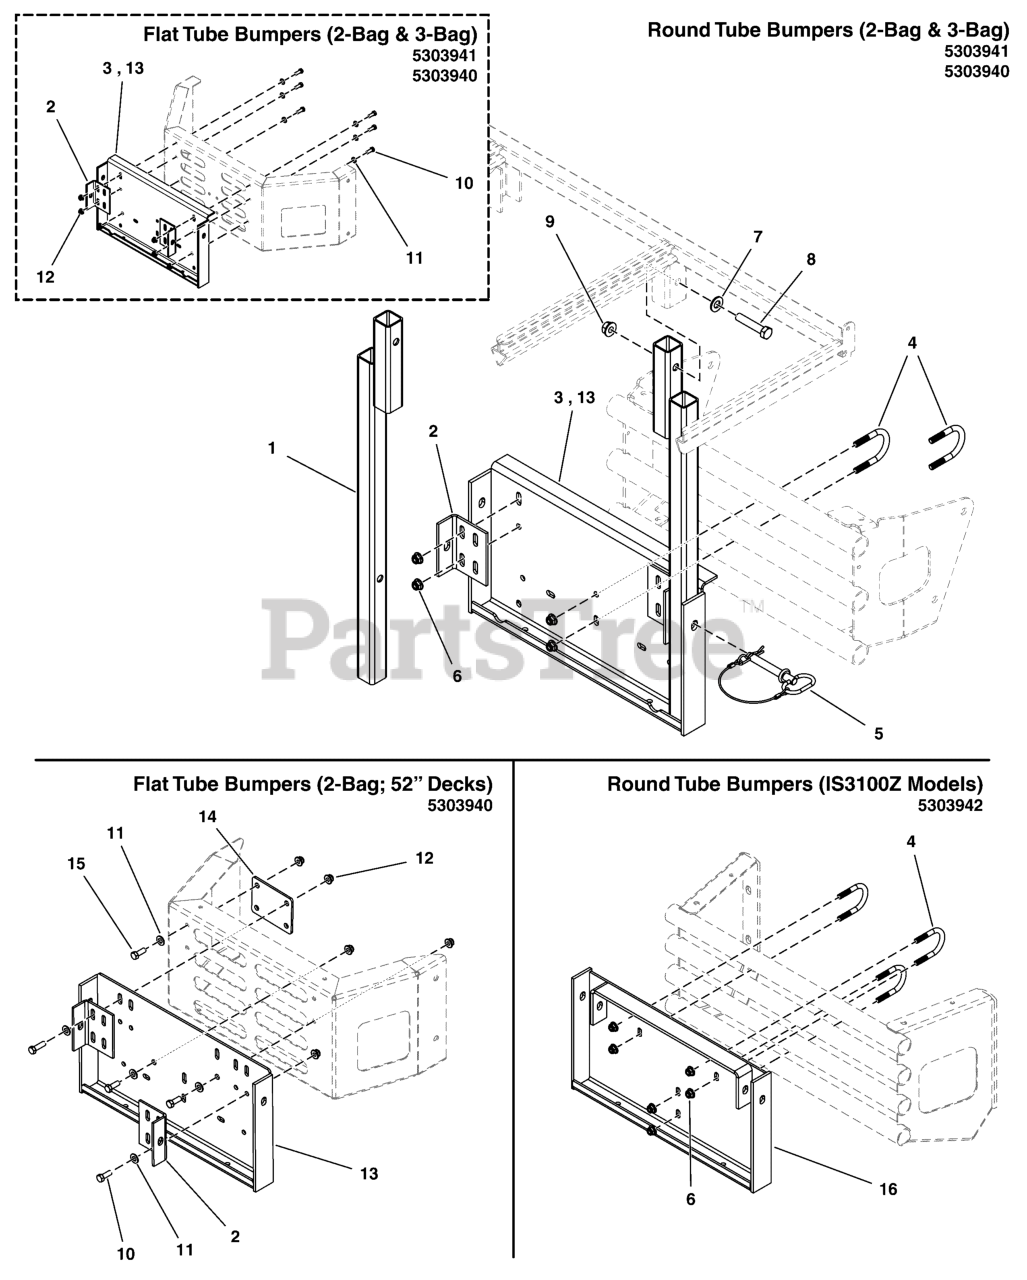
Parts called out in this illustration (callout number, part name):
1	WELD, HARD TOP, MOUNTING POST - BLK
2	BRACKET, BAGGER MOUNT - BLK
3	WELD, BAGGER MNT,1500/4500-BLK
4	U-BOLT, 3/8" X 1-1/4"
5	PIN, HITCH, .50 X 3.25 W/ LAY (SV)
6	NUT, 3/8 - 16 HEX NYLOCK FLANGE
7	WASHER, 1/2 SAE
8	BOLT, 1/2-13 X 2-1/2" GD5 CZ
9	NUT, Hex Flange, Nylock, 1/2-13
10	BOLT, 3/8-16 X 1" GD5 CZ
11	WASHER, 3/8 SAE
12	NUT, 3/8 - 16 HEX NYLOCK FLANGE
13	WELD, 2 BAG MOUNT - BLK
14	PLATE, PECO MOUNT - BLK
15	BOLT, 3/8-16 X 1-1/4" GD5 CZ
16	WELD, BAGGER MOUNT, IS3100Z - BLK
